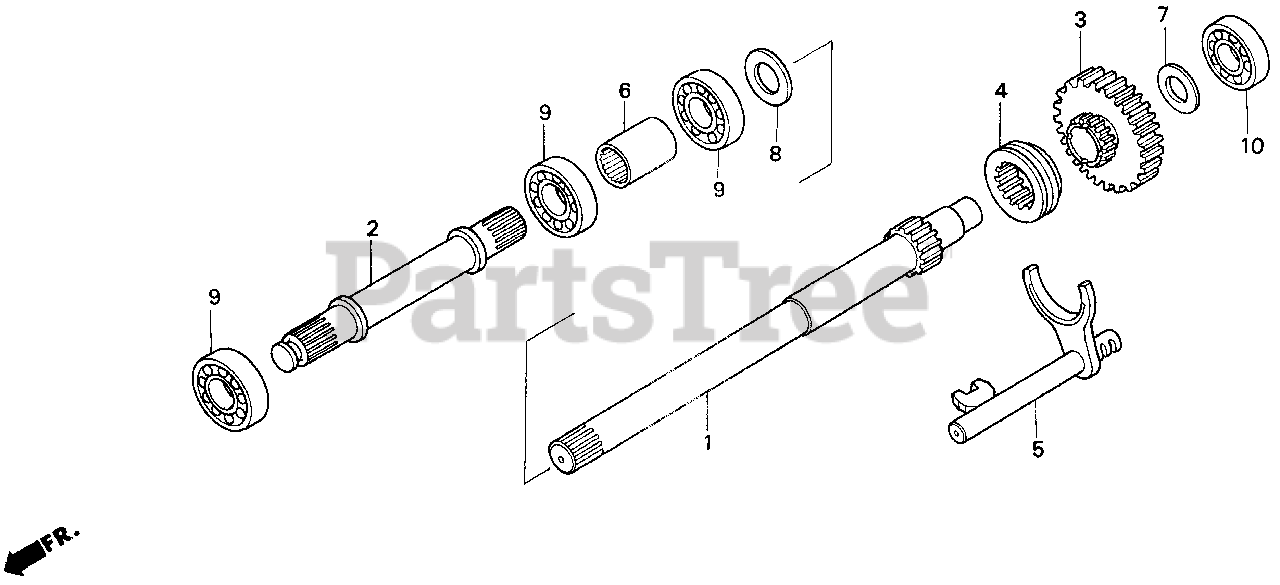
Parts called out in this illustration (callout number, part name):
1	SHAFT A, FR. DRIVE
2	SHAFT B, FR. DRIVE
3	GEAR, FR. DRIVEN (31T)
4	SELECTOR, CHANGE (2/4WD)
5	FORK, SHIFT (2/4WD)
6	COLLAR, JOINT
7	WASHER, THRUST (20X31.5)
8	WASHER, THRUST (22X39X2)
9	BEARING, RADIAL BALL (62/22)
10	BEARING, RADIAL BALL (6204)
